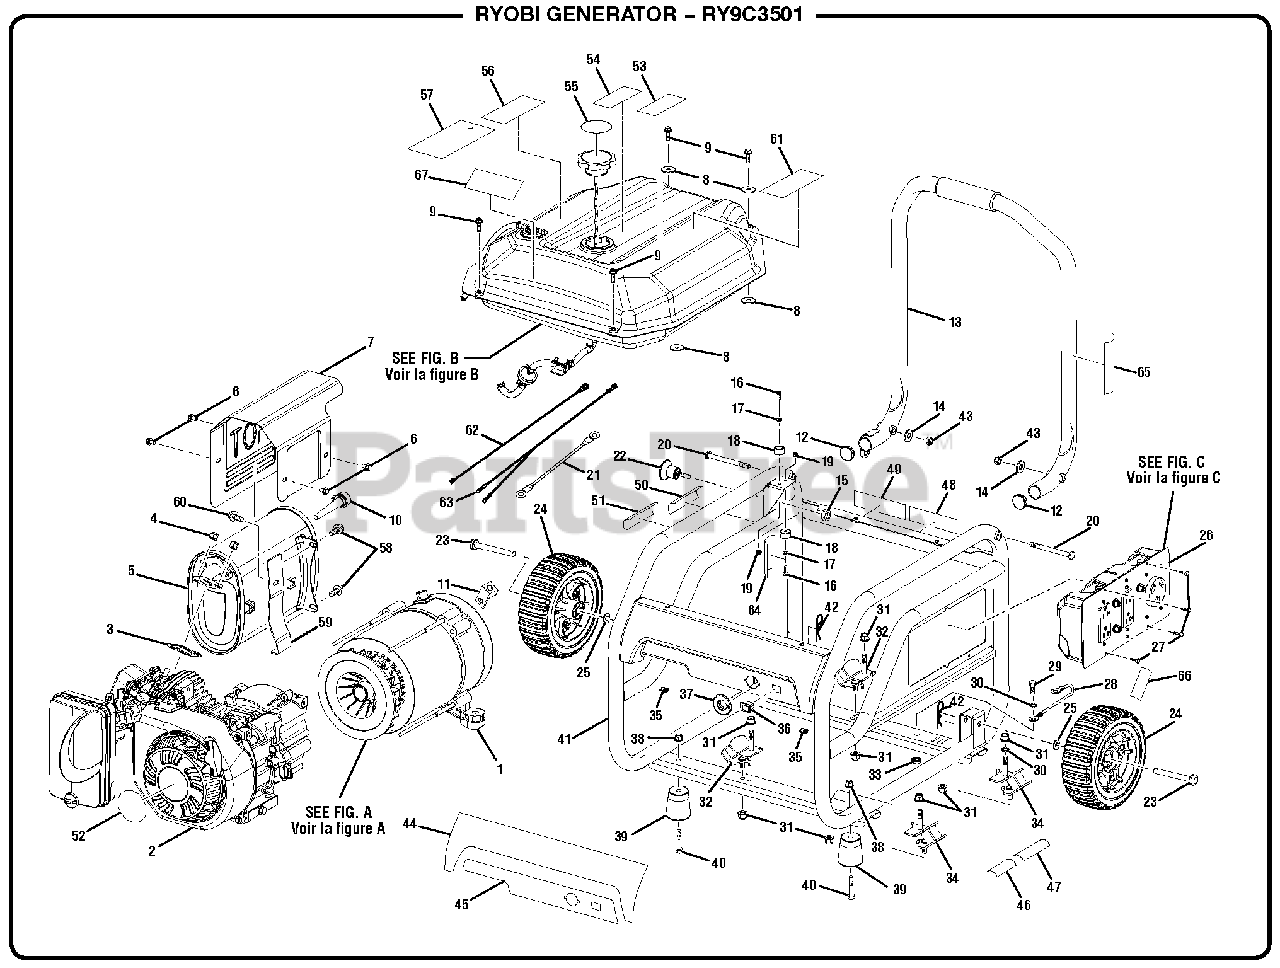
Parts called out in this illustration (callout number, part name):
1	Generator Head Assembly
2	Engine (RATO R210)
3	Muffler Gasket
4	Lock Nut (M8)
6	Bolt (M6 x 10 mm, Flange Hd.)
7	Heat Shield
8	Washer (1/4 in.)
9	Bolt (M6 x 1 in., Hex Hd.)
10	Spark Arrestor
11	Ground Lug
13	Handle Assembly
14	Washer (5/16 in.)
15	Nut (1/2-20)
16	Bolt (M4 x 12.5 mm, Hex Hd.)
17	Washer (M4)
18	Rubber Bumper
19	Flange Nut (M4)
20	Handle Pin
21	Bonding Wire
22	Handle Release Pin
25	Washer (M10)
26	Control Panel Assembly
27	Screw (6-20 x 3/8 in., Type B)
28	Ground Wire Assembly
29	Bolt (5/16-18 x 3/4 in.)
30	Star Washer (5/16 in.)
31	Lock Nut (M8)
32	Isolator (Left)
33	Hex Nut (5/16-18)
34	Isolator (Right)
35	U-Clip (M6)
36	Stop Switch
37	Fuel Valve Bezel
38	Lock Nut (M8)
40	Bolt (M8 x 45 mm, Flange Hex Hd.)
41	Carrier Assembly
42	Hitch Pin
43	Lock Nut (5/16-18)
44	Performance Label
45	Start Label
46	Inquires Label
47	Lubricant Label
48	Ground Warning Label
49	Fire Danger Label
50	Hot Surface Label
51	Combustion Label
52	Recoil Label
53	CPSC Label
54	E-85 Label
55	Fuel Stabilizer Label
56	Danger Label
57	Warning Hangtag
58	Bolt (M8 x 1.25 in., Flange Hex Hd.)
59	Muffler Bracket
60	Bolt (M6 x 14 mm, Flange Hex Hd.)
61	Fire Danger Label
62	Wire Assembly (Green)
63	Wire Assembly (Black)
64	Handle Release Label
65	Fuel Stabilizer Label (Spanish)
66	Logo Label (Small)
67	Logo Label (Large)
